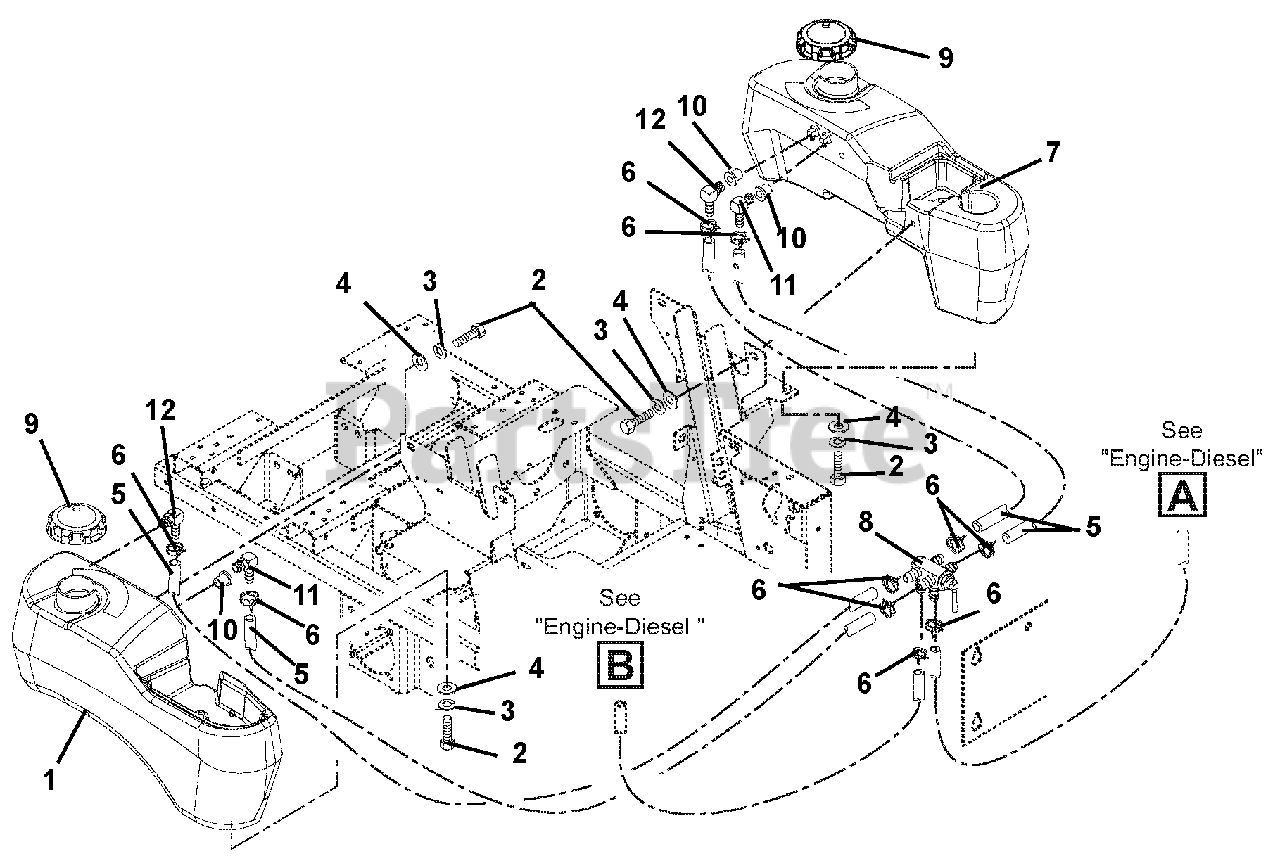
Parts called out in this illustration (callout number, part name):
1	Tank, Fuel-Right Hand
2	Bolt, Hex .31-18 x .75 Grade 5
3	Washer, Locking .31 x .078
4	Washer, Flat Steel .38 x .875 x .083
5	Hose, .31 ID
6	Clamp, Hose Wire .52/.55
7	Tank, Left Hand Fuel (EYE-Q) 200 Series-EFI
8	Valve, Fuel
9	Cap, Fuel
11	Fitting, Tank
12	Fitting, Tank
